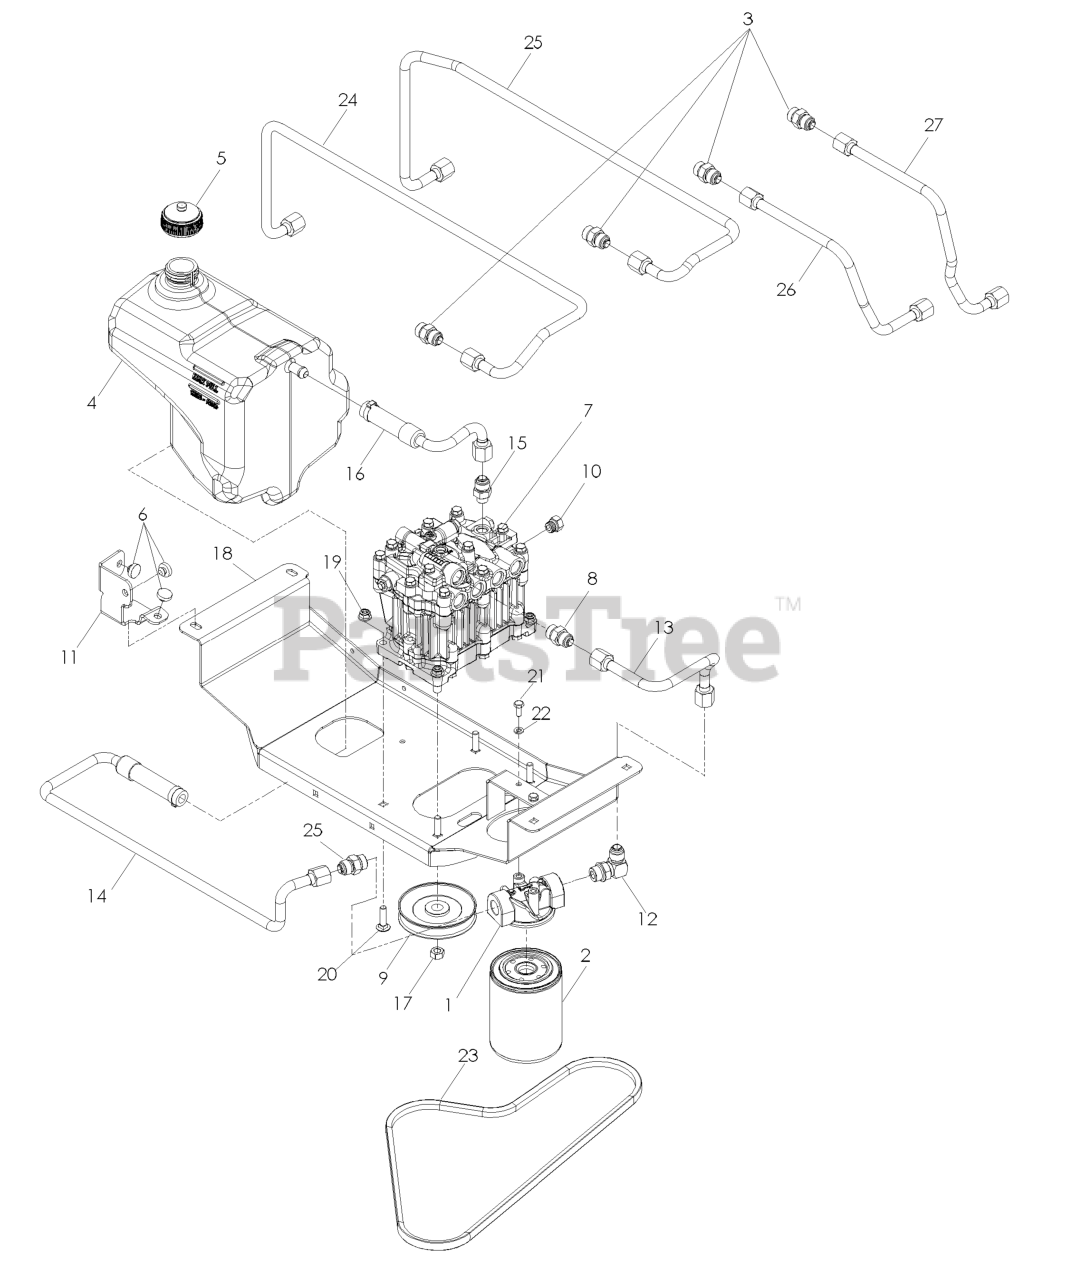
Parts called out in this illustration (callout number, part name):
1	FILTER HEAD
2	HYDRAULIC OIL FILTER
3	FITTING, STRAIGHT F6400-8-8-0
4	RESERVOIR HYDRO
5	HYDRAULIC CAP
6	GROMMET, BUMPER
7	PUMP, DUP10S (77808041201)
8	FITTING, 10-8 STRAIGHT
9	PULLEY, PUMP
10	PLUG, 6408-6
11	SUPPORT, RESERVOIR
12	FITTING, 10-8 90 DEG
13	HYD LINE, CHARGE
14	HYD LINE, INLET
15	FITTING, HYDRO
16	HYDRO LINE, CASE
17	NUT M10-1.5 L/H HEX
18	PLATE, PUMP
19	5/16-18 NYLOC FLANGE NUT
20	BOLT, CARRIAGE 5/16X1-1/4
21	HCS 1/4C X 5/8
22	LOCKWASHER 1/4"
24	HYDRO LINE, A
24	HYDRO LINE, 72A
24	HYDRO LINE, B
24	HYRO LINE, 72B
24	HYDRO LINE, C
24	HYDRO LINE, 72C
24	HYDRO LINE, D
24	HYDRO LINE, 72D
